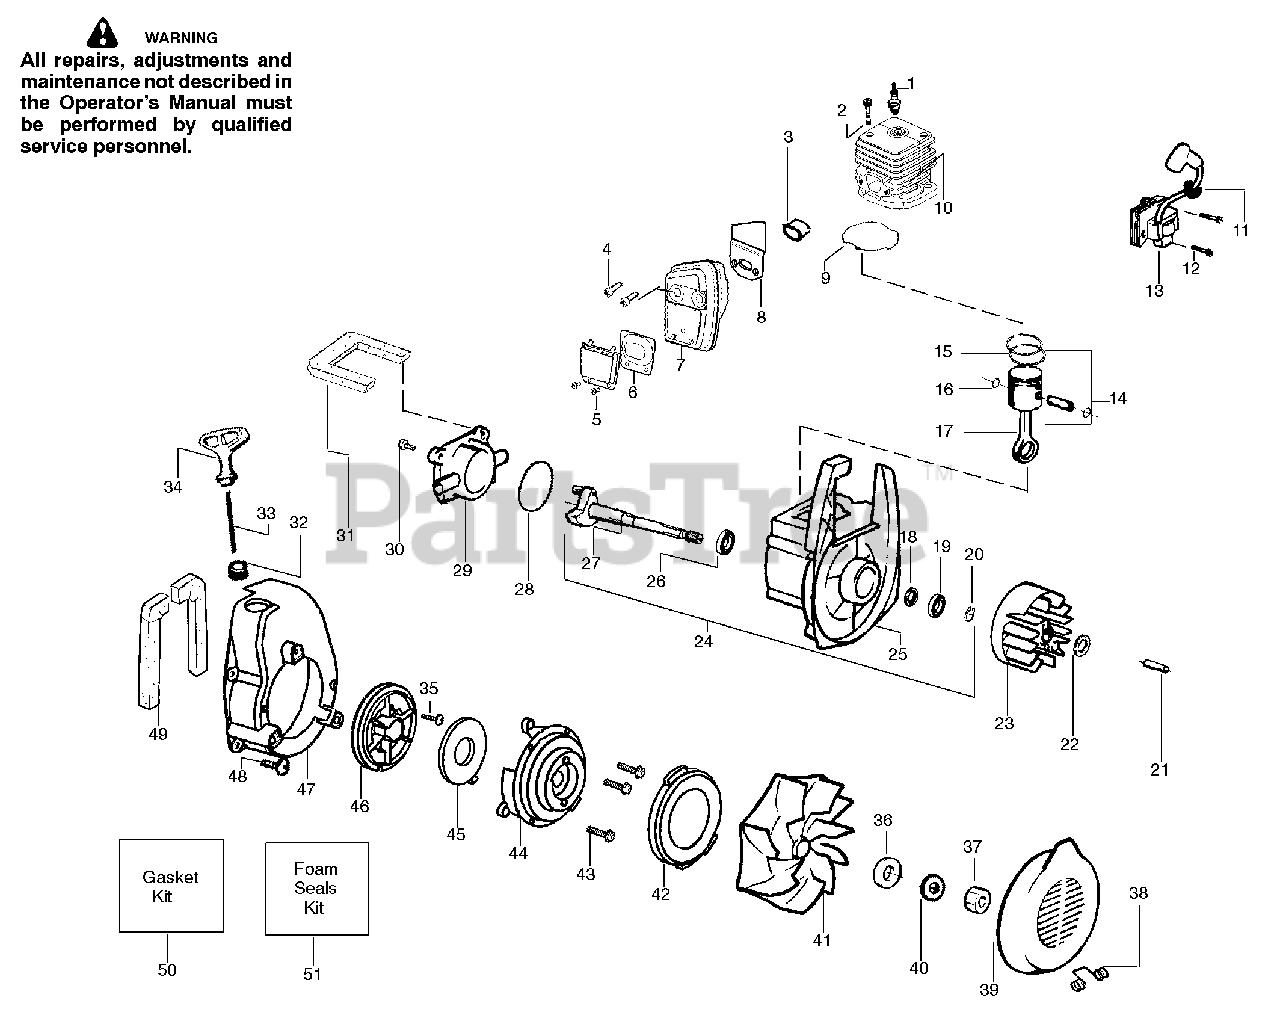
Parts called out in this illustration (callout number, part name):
1	Spark Plug (RCJ-6Y)
3	Insulator-Heat
6	Kit-Spark Screen
7	Kit-Muffler
8	Gasket-Baffle (kit)
9	Gasket-Cylinder (kit)
10	Kit-Cylinder
11	Grommet-Ign. Module
12	Screw-Ignition Module
13	Ignition Module
14	Kit-Piston
15	Piston Ring
16	Retainer-Piston Pin
17	Assy-Connecting Rod
18	Seal-Crankcase
19	Bearing-Outer
20	Retainer Ring-C'chaft
21	Spacer-Flywheel
23	Assy-Flywheel
24	Assy-Crankcase/Crankshaft
25	Assy-Crankcase
26	Bearing-Inner
27	Assy-Crankshaft
28	O-ring-C/case (kit)
29	Cover-Crankcase
30	Screw
31	Foam-219mm (kit)
32	Eyelet-Flange
33	Kit-Rope
34	Handle-Starter
35	Screw-Rope
36	Washer-Flat
38	Spring-Return Cover
39	Inlet Door
40	Washer-Belleville
41	Assy-Impeller
42	Seal-Ring
44	Housing-Pulley
45	Spring-Starter
46	Kit-Starter Pulley
47	Fan Housing
48	Screw
49	Foam-365mm (kit)
50	Kit-Gasket
51	Kit-Foam Seals
